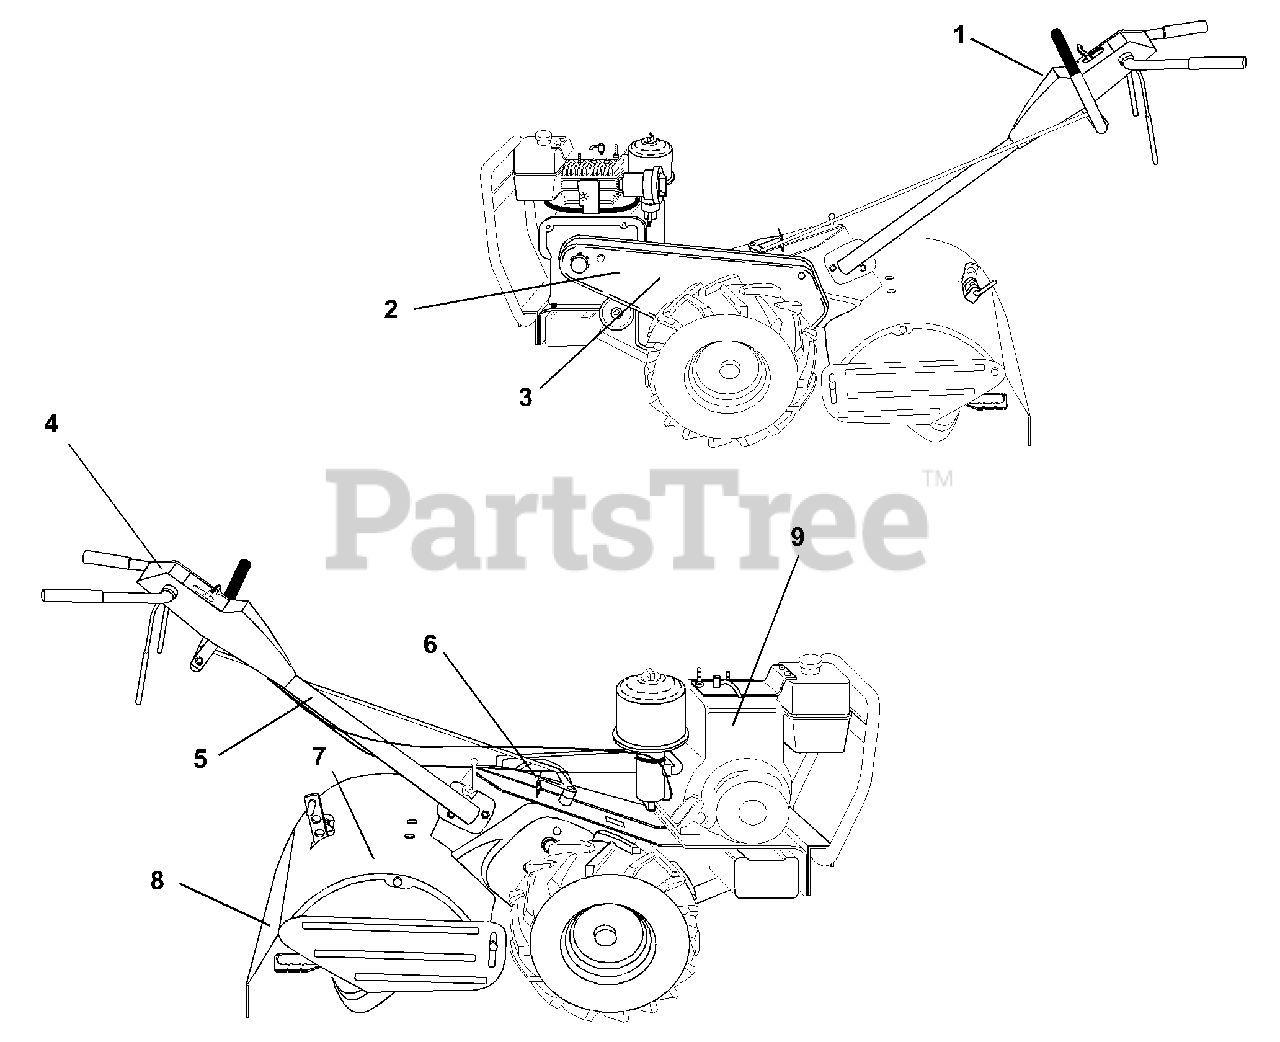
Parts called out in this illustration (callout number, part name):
1	Decal, Logo
2	Decal, Logo
3	Decal, Nameplate
4	Decal, Instruction, Tilling
5	Decal, Hand Placement
6	Decal, Shift Indicator
7	Decal, Caution
8	Decal, Warning, Rotating Tines
9	Decal, Briggs & Statton
